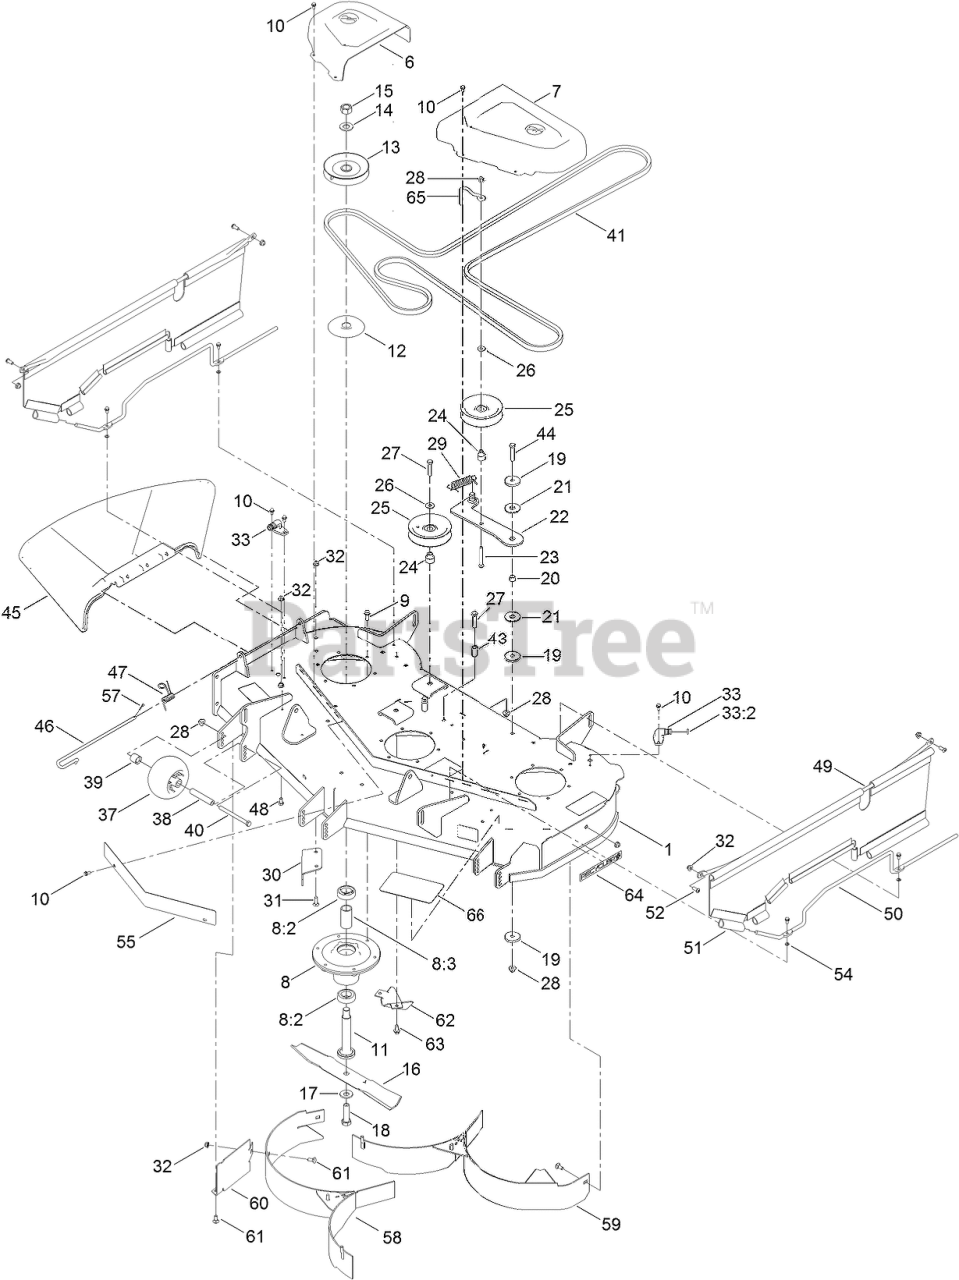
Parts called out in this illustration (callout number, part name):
1	DECK ASM
6	COVER-BELT, RH
7	COVER-BELT, LH
8	SPINDLE ASM
8:2	BEARING-BALL
8:3	SPACER-BEARING
9	SCREW-TAPTITE
10	SCREW-HWH
11	SHAFT-SPINDLE
12	SHIELD-BEARING
13	PULLEY
14	WASHER
15	NUT-HEX
16	BLADE-MULCH, 16.50 INCH
17	WASHER-BELLEVILLE
18	SCREW-BLADE
19	WASHER-PLAIN
20	SPACER
21	WASHER-FRICTION, COMPOSITE
22	IDLER ARM ASM
23	SCREW-CARR
24	BUSHING-IDLER
25	PULLEY-IDLER, FLAT
26	WASHER-HARDENED
27	SCREW-HH
28	NUT-HF, NI
29	SPRING-EXTENSION
30	BAFFLE-CUTOFF
31	SCREW-CARR
32	NUT-HF
33	FITTING-WASHOUT
33:2	O-RING
37	ROLLER-SCALP, ANTI
38	TUBE-SPANNER
39	SPACER-AXLE, REAR
40	SCREW-HH
41	V-BELT
43	SPACER-FENDER
44	SCREW-HH
45	DEFLECTOR-DISCHARGE
46	PIN-CHUTE
47	SPRING-TORSION
48	SCREW-HH
49	ROD SUPPORT, UPPER
50	ROD SUPPORT, LOWER
51	SIDE GUARD ASM
52	SCREW-HSBH
54	NUT-RETAINING
55	SHIELD-FRONT
57	PIN-COTTER
58	BAFFLE-RECYCLER
59	BAFFLE-RECYCLER
60	GUARD-BAFFLE
61	BOLT-CARR
62	KICKER-FLANGED
63	SCREW-HWHTF
64	DECAL-RECYCLER
65	GUIDE-BELT, IDLER
66	TREAD-STEP
